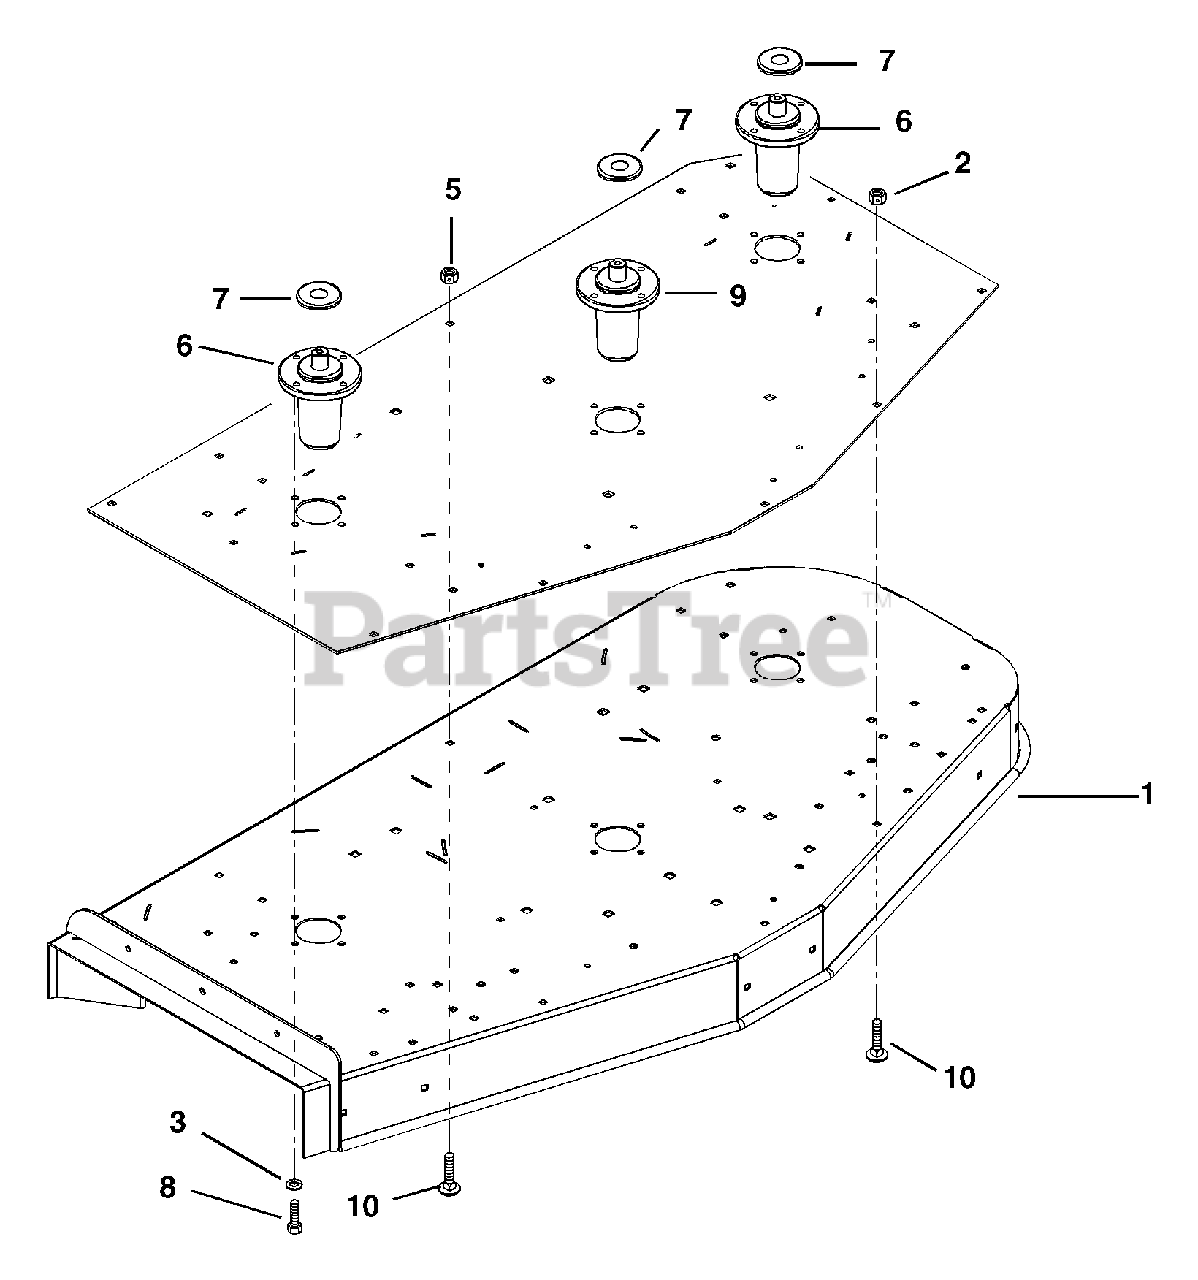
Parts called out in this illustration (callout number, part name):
1	Weldment, 72" Deck
2	Plate, 72" Reinforcement
3	Washer-Locking .38 x .094
4	Bolt-Round Head Square Neck .38 - 16 x 2.75 Grade 5
5	Nut-Locking-Nylon .38 - 16
6	Assembly, Spindle L-Hub
7	Slinger-Dust
8	Bolt-Hex .38 - 16 x 1.00 Grade 5
9	Assembly, Spindle
10	Bolt-Round Head Square Neck .38 - 16 x 1.00 Grade 2
